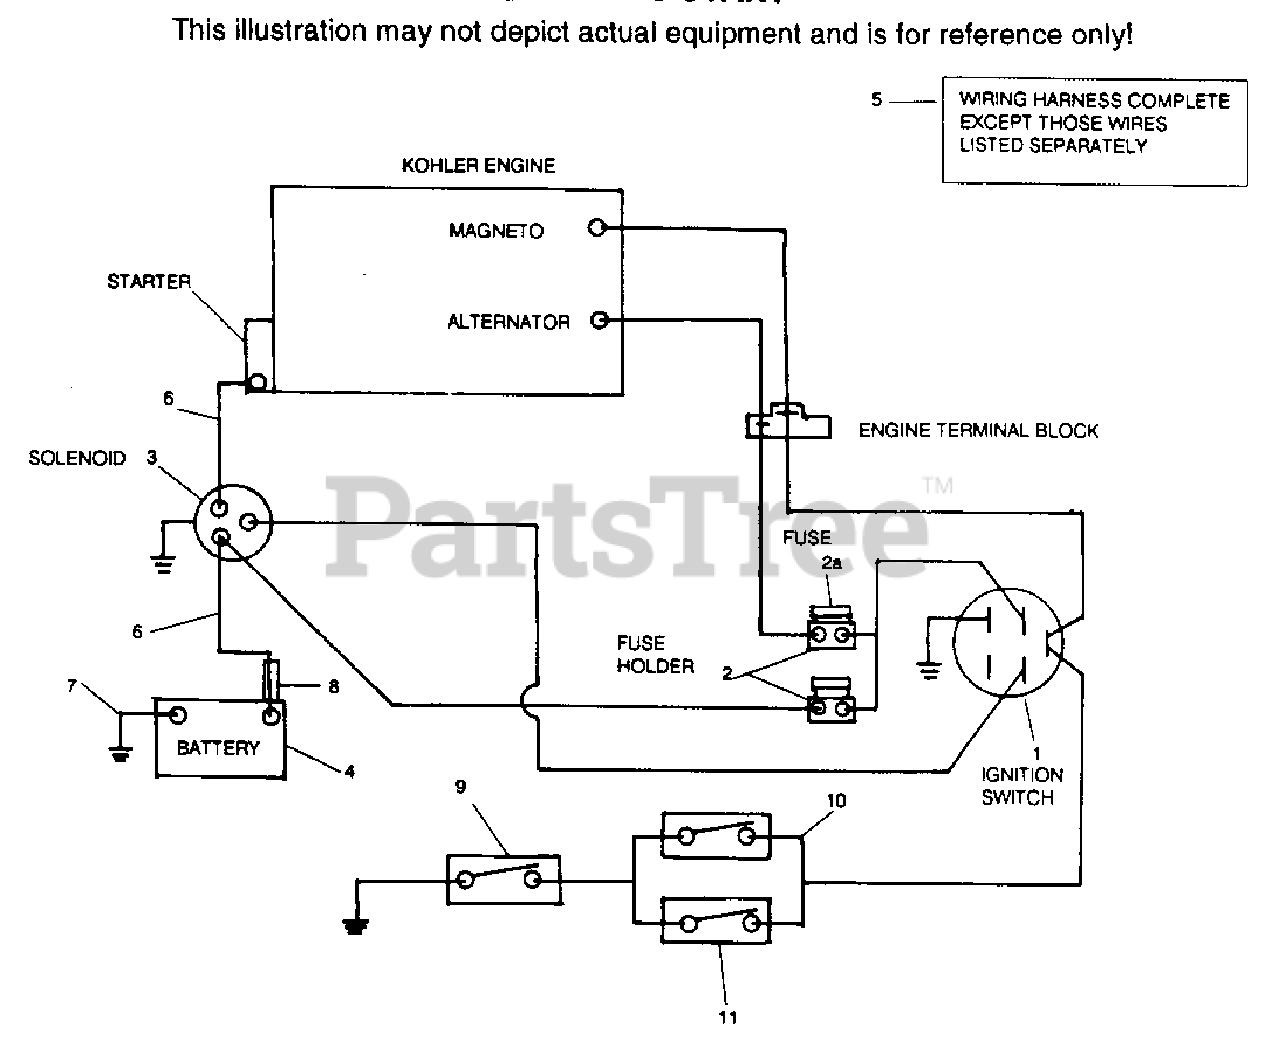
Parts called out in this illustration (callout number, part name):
1	KEY SWITCH
2	FUSE HOLDER
2A	FUSE 20 AMPS
3	SOLENOID
4	BATTERY MAY BE PURCHASED LOCALLY(U9-LM)
5	WIRING HARNESS COMPLETE
6	BATTERY CABLE - 13-3/4" RED
7	BATTERY CABLE - 13-3/4" BLACK
8	RUBBER BOOT
9	SWITCH, HANDLE INTERLOCK N.C.
10	SWITCH, CUTTER DRIVE INTERLOCK N.C.
11	SWITCH, NEUTRAL INTERLOCK N.C.
